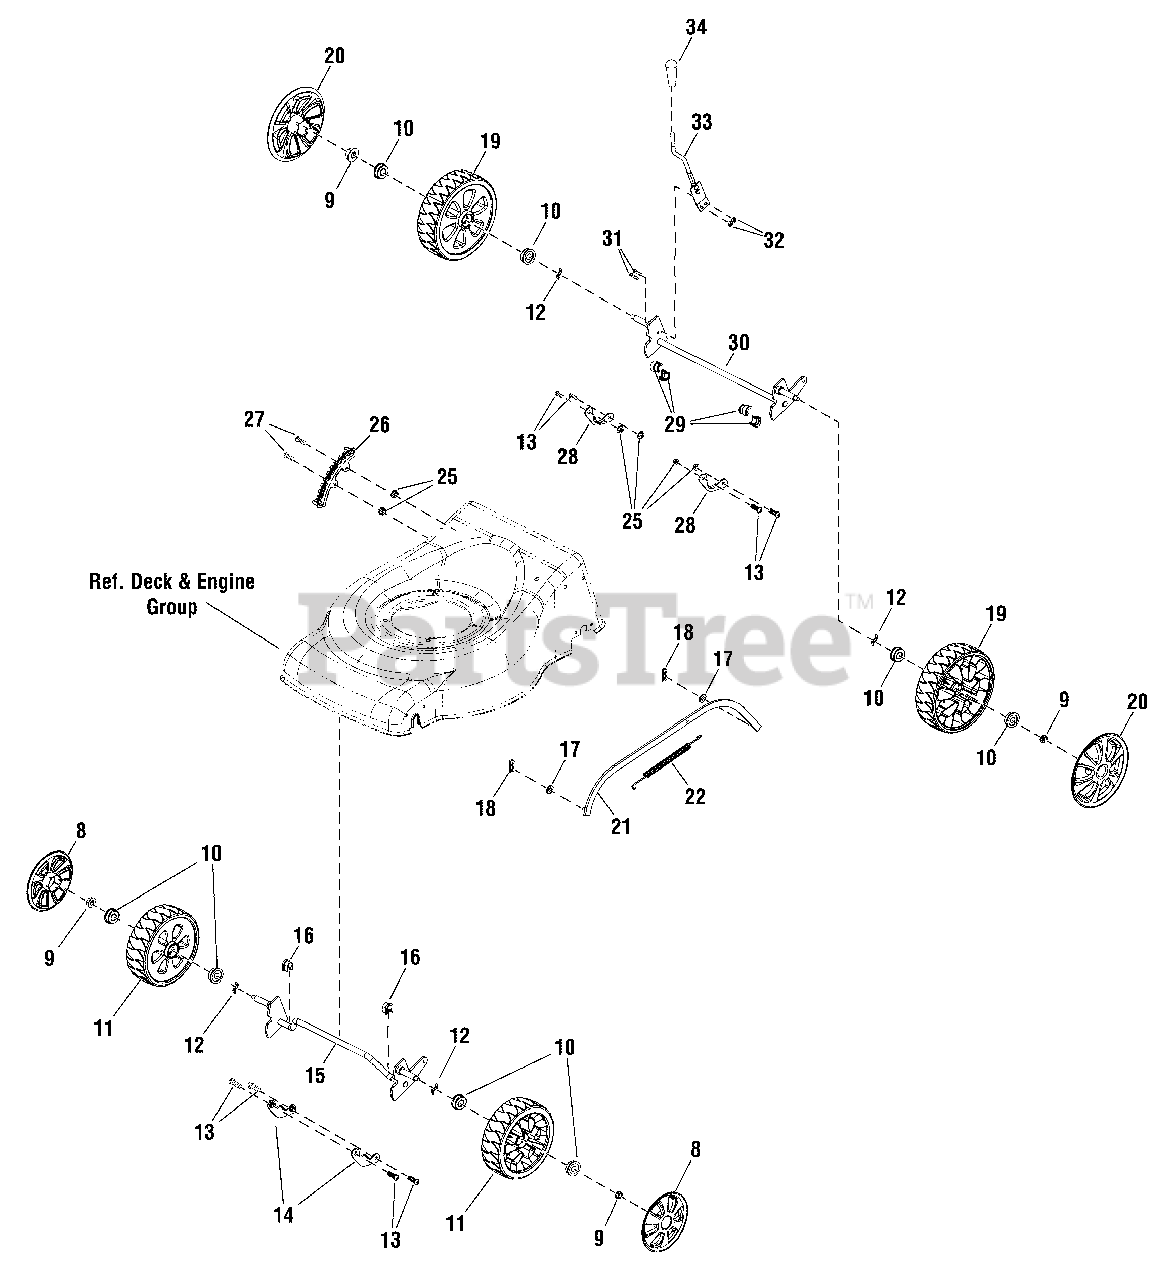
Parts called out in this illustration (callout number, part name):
8	HUBCAP, Front
9	* NUT, Hex Lock
10	BEARING
11	WHEEL ASSEMBLY, Front
12	WASHER, Wave
13	* SCREW
14	BRACKET, Wheel Axle, Front
15	AXLE, Front
16	CLAMP, Axle, Front
17	* WASHER, Flat
19	WHEEL ASSEMBLY, Rear
20	HUBCAP, Rear
21	CONNECTING LINK
25	* NUT, Hex Lock
26	BRACKET, Height Adjustment
27	* SCREW
28	BRACKET, Wheel Axle, Rear
29	BEARING HOLDER
30	AXLE, Rear
31	* SCREW
32	* NUT, Hex Lock
33	LEVER, Height Adjust
